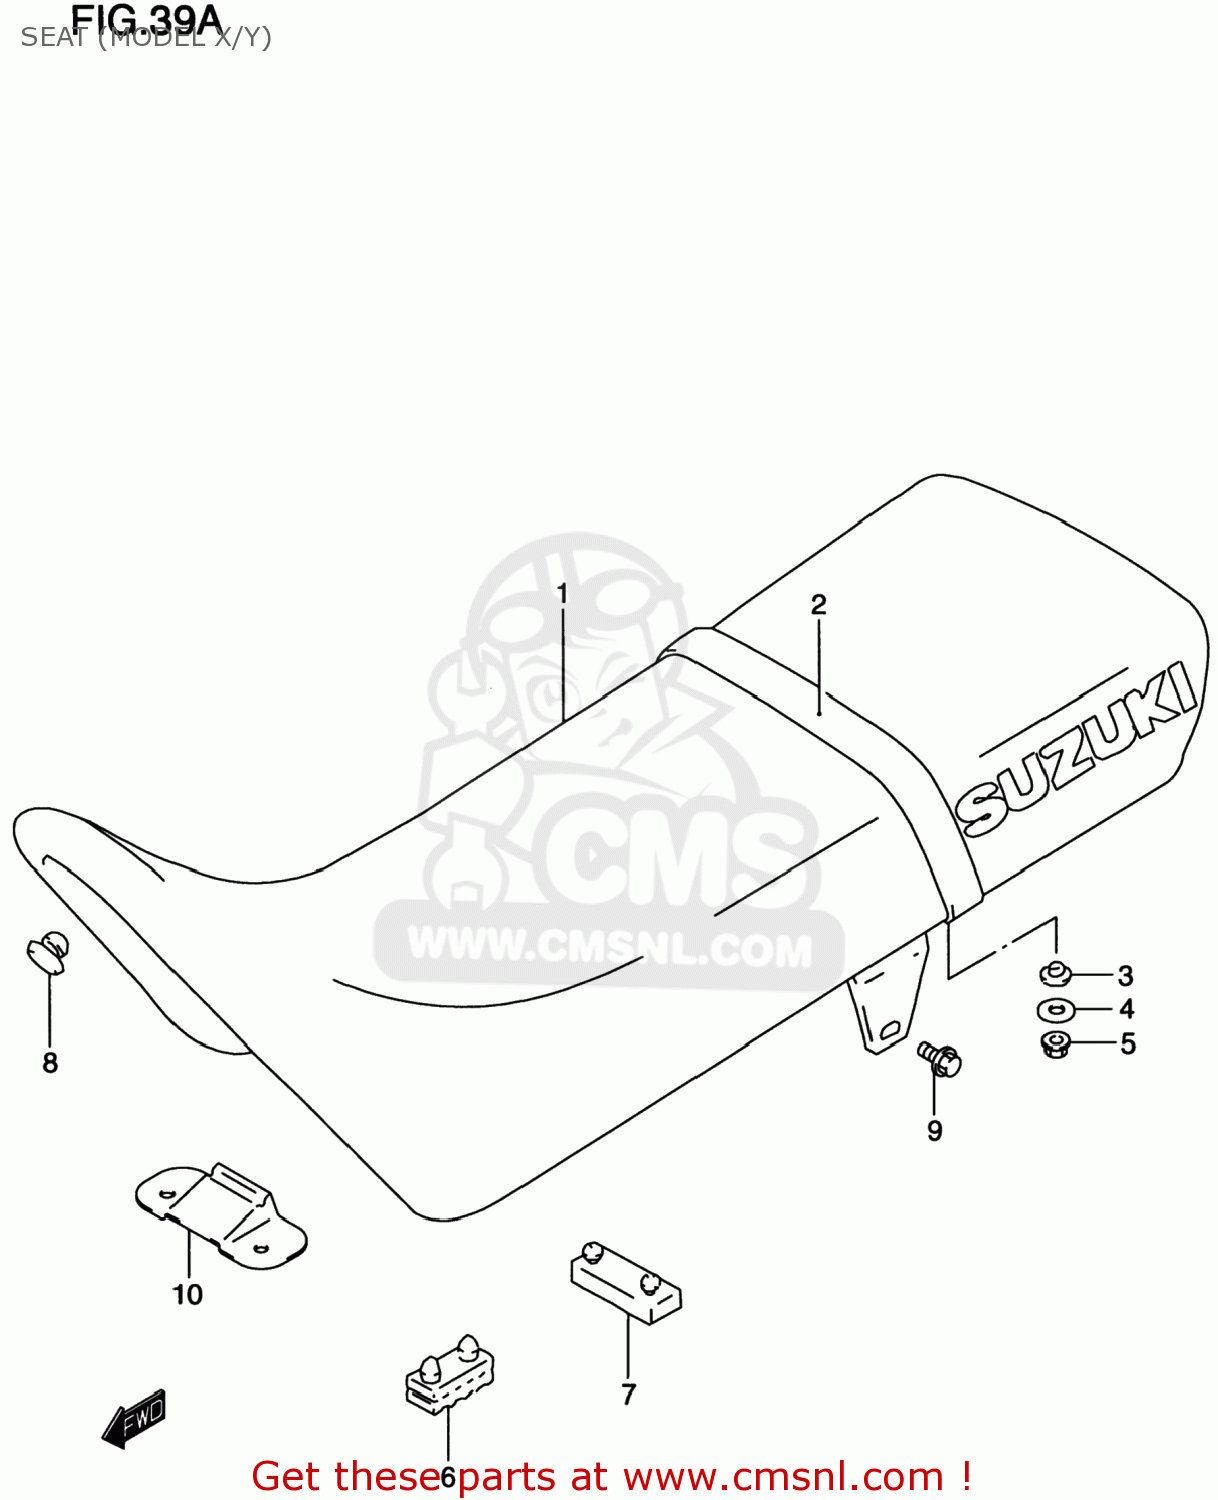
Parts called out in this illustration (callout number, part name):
1	SEAT SET
2	BAND,SEAT
3	WASHER
4	WASHER
5	NUT
6	CUSHION,SEAT(40X20X15)
7	CUSHION,SEAT
8	CUSHION
9	BOLT
10	PLATE,SEAT FR HOOK
